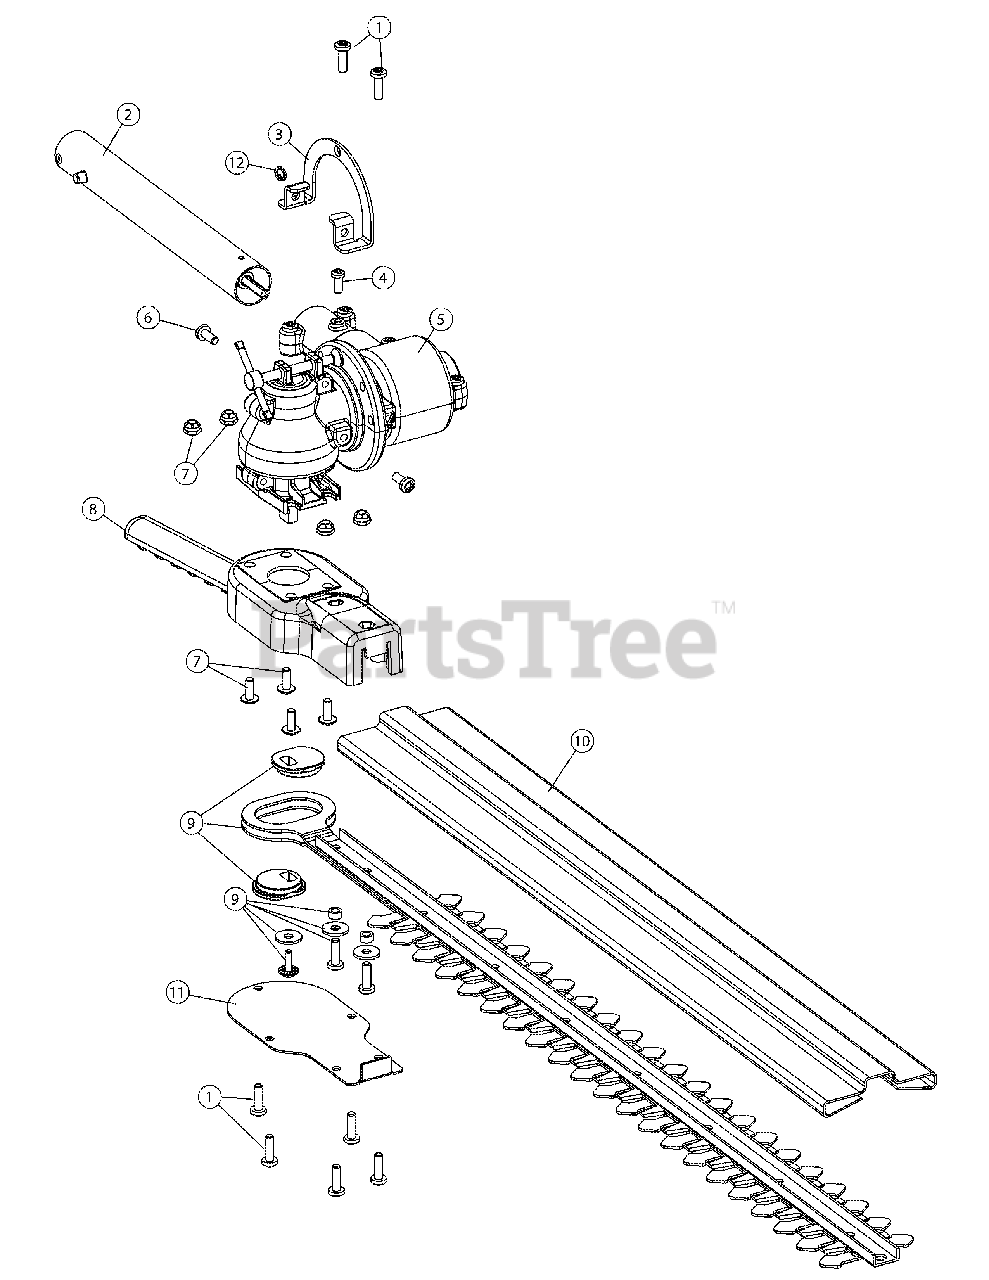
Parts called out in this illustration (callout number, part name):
2	Drive Shaft Housing Assembly
3	Indexing Ring
4	Anti Rotation Screw
5	Gearbox Assembly
6	Screw
7	Blade Housing Hardware
8	Upper Blade Housing
9	Blade Assembly
10	Guard
11	Lower Blade Assembly
12	Lock Washer
